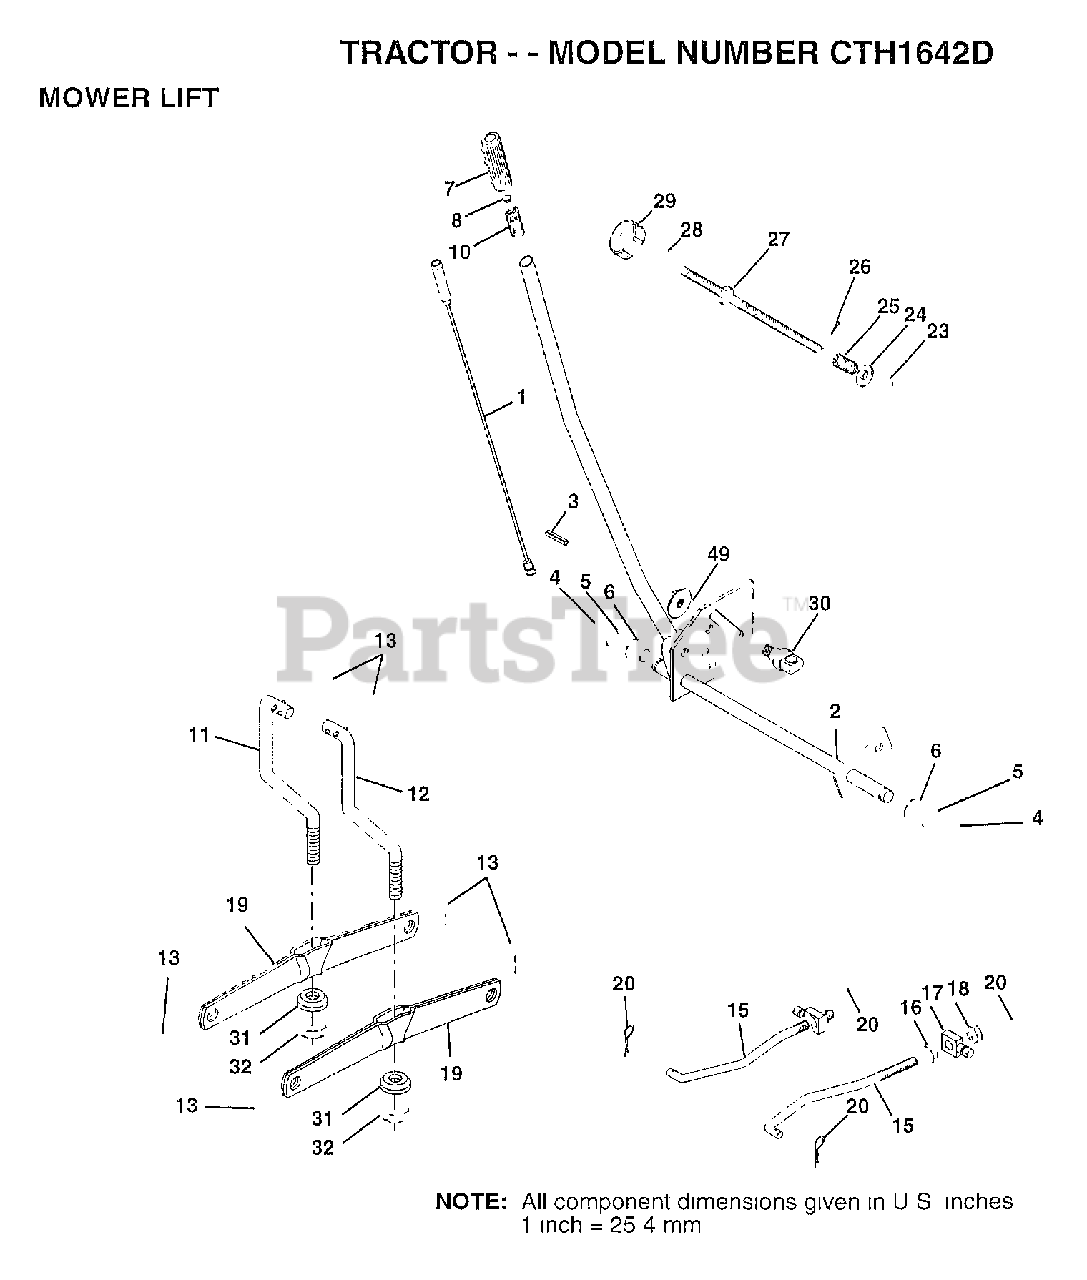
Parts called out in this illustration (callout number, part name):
1	WIRE ASM
2	SHAFT.ASM.LIFT
3	PIN GROOVE
5	WASHER
6	NYLON BEARING
7	GRIP
15	LINK.FRONT
16	NUT
17	TRUNION
18	NUT.LK.W/WSH.1/2.
19	ARM SUSP REAR
20	RETAINER.SPRING
23	NUT T
24	WASHER
25	SPRING.COMP.INF.H
27	ROD.ADJ.LIFT
28	NUT
29	KNOB INF 3/8-16
30	TRUNNION
31	BEARING PVT LH
32	NUT.CROWNLOCK.3/8
49	NUT.HXFLG.LOCK.
